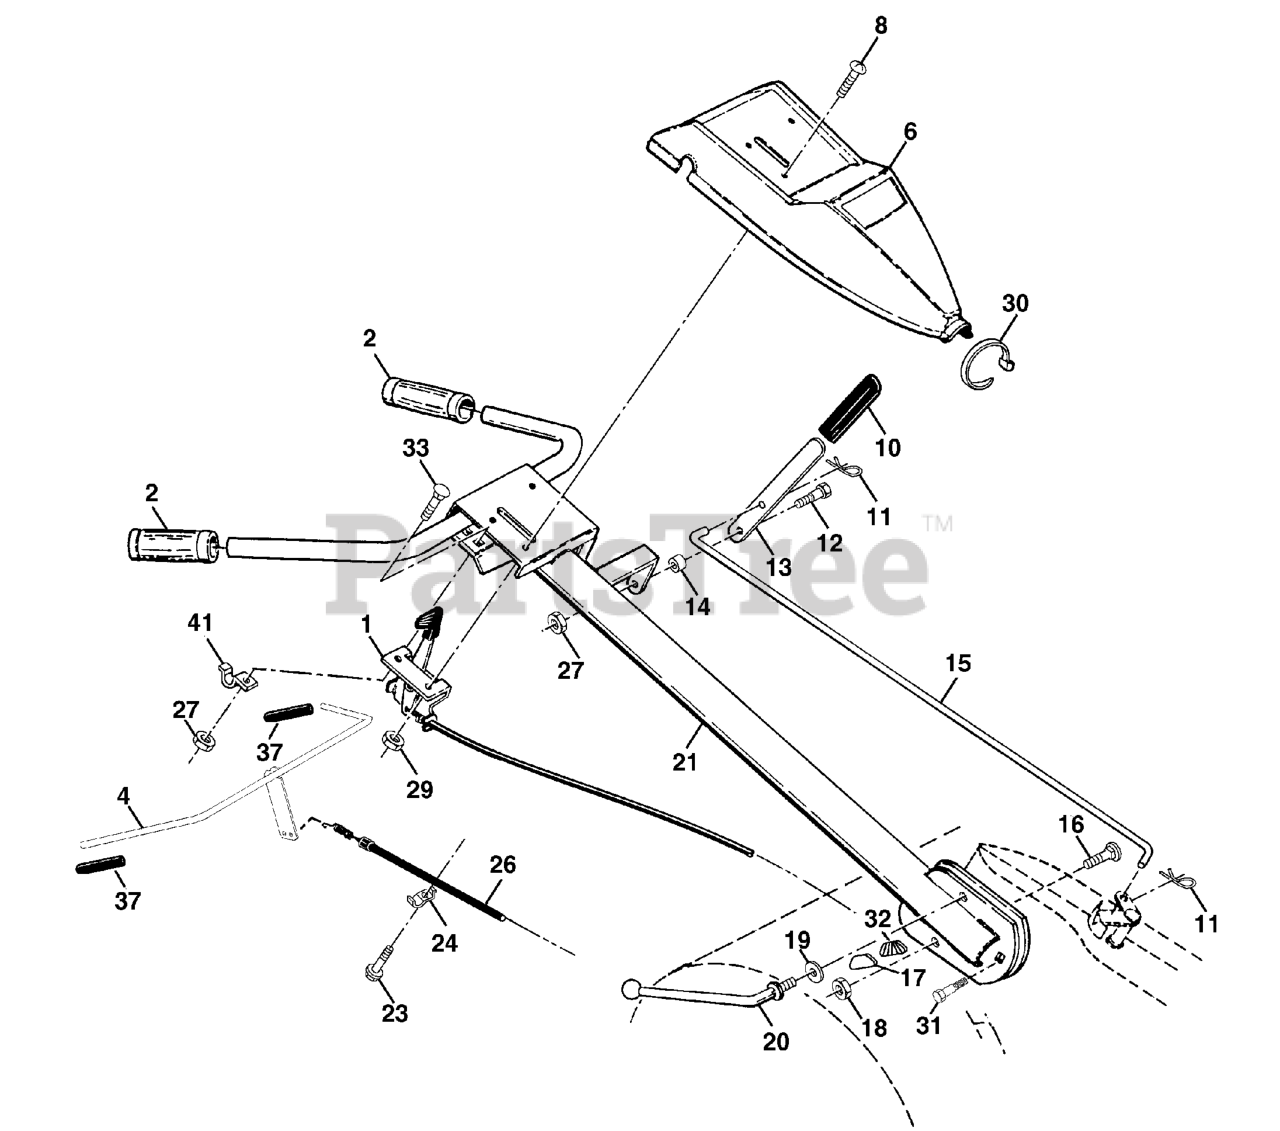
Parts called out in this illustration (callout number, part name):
1	Control, Throttle
2	Grip, Handle
4	Bar Assembly, Control
6	Panel, Control
8	Screw, Pan Hd. #10-24 UNC
10	Grip, Handle
11	Clip, Hairpin
12	Bolt, Shoulder
13	Handle, Shift
14	Grommet, Rubber
15	Rod, Shift
16	Bolt, Carriage 3/8-16 x 1
17	Lock, Handle
18	Nut, Crownlock 3/8-16 UNC
19	Washer 13/32 x 1 x 11 Ga.
20	Lever, Lock, Handle
21	Handle
23	Screw, Hex Washer Hd. Slotted #10-24 x 1/2
26	Cable, Clutch
27	Nut, Hex Flange 1/4-20 UNC
29	Nut, Keps #10-24 UNC
30	Tie, Cable
31	Bolt, Pivot
32	Lock, Handle
33	Bolt, Carriage 1/4-20 UNC x 1/2
37	Grip, Bar, Control
41	Clamp, Bar, Control
